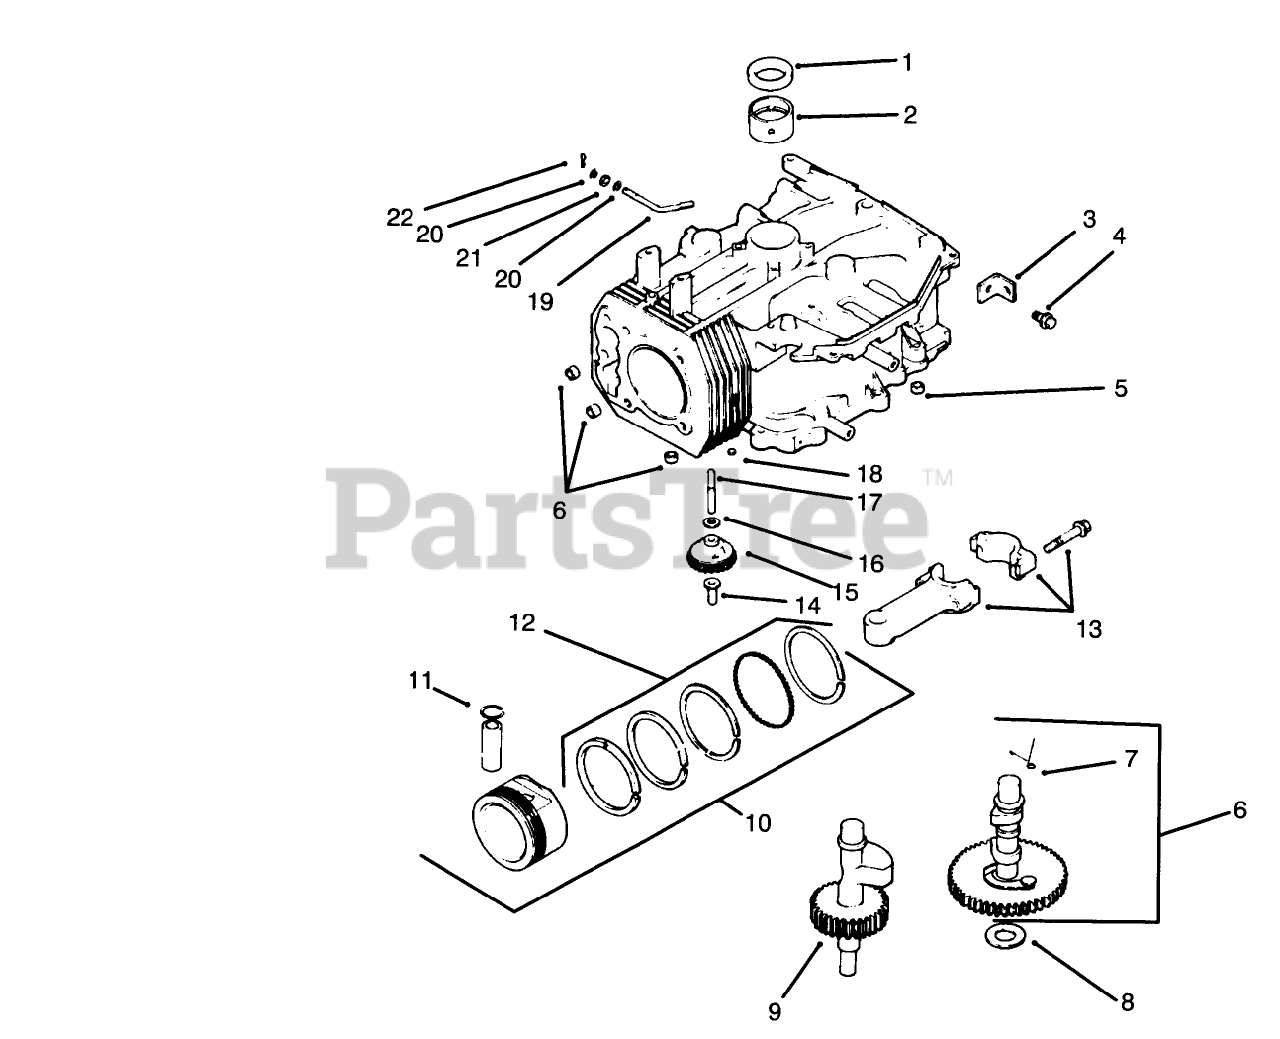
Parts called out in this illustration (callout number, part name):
1	Seal-Crankshaft (Only On: 72042, 72043, 72062, 72063)
2	Bearing-Crankshaft
3	Strap-Lifting (Only On: 72042,72043,72062,72063)
5	Pin-Dowel
6	Camshaft Assembly
7	Spring-Actuating (Only On: 72042,72043,72062,72063)
8	Shim-Camshaft
9	Shaft-Balance
10	Piston W/Ring Set (Std.)
11	Retainer-Piston Pin (Only On: 72042, 72043,72062,72063)
12	Ring Set STD (Only On: 72042,72043,72062,72063)
13	Connecting Rod STD (Only On: 72042, 72063, 72062, 72043)
14	Pin-Governor
15	Gear-Governor ASM (Only On: 72042, 72063, 72062, 72043)
17	Shaft-Govenor Gear
19	Shaft-Governor Cross (Only On: 72042, 72063, 72062, 72043)
20	Washer-Governor Shaft (Only On: 72042, 72063, 72062, 72043)
21	Seal
22	Pin-Hitch
